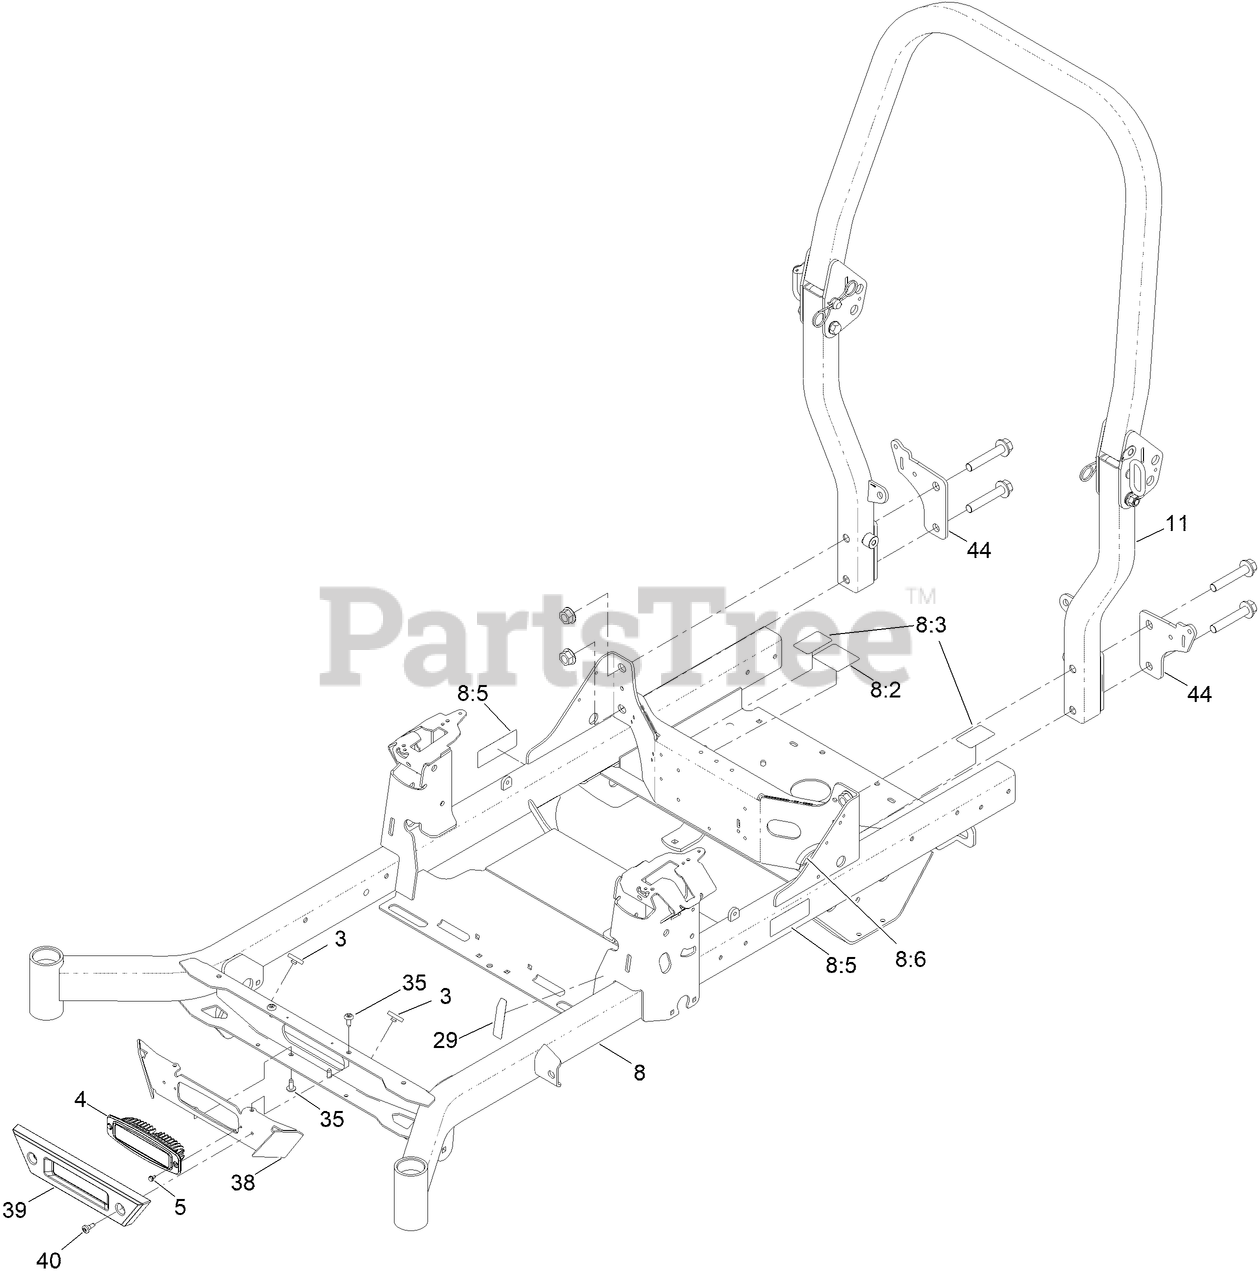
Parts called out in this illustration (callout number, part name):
3	BUMPER-PUSH-IN, RUBBER
4	MOUNT-FLUSH, LIGHT
5	SCREW-HWH
8	FRAME-60, MR
8:2	DECAL-ROUTING, BELT
8:3	DECAL-RELEASE, DRIVE
8:5	DECAL-WARNING
8:6	STRIP-SEAL
11	ASM-ROPS, MR
29	DECAL-FILL, FUEL
38	BRACKET-LIGHT [RED]
39	BUMPER-FRONT
40	SCREW-SHOULDER
